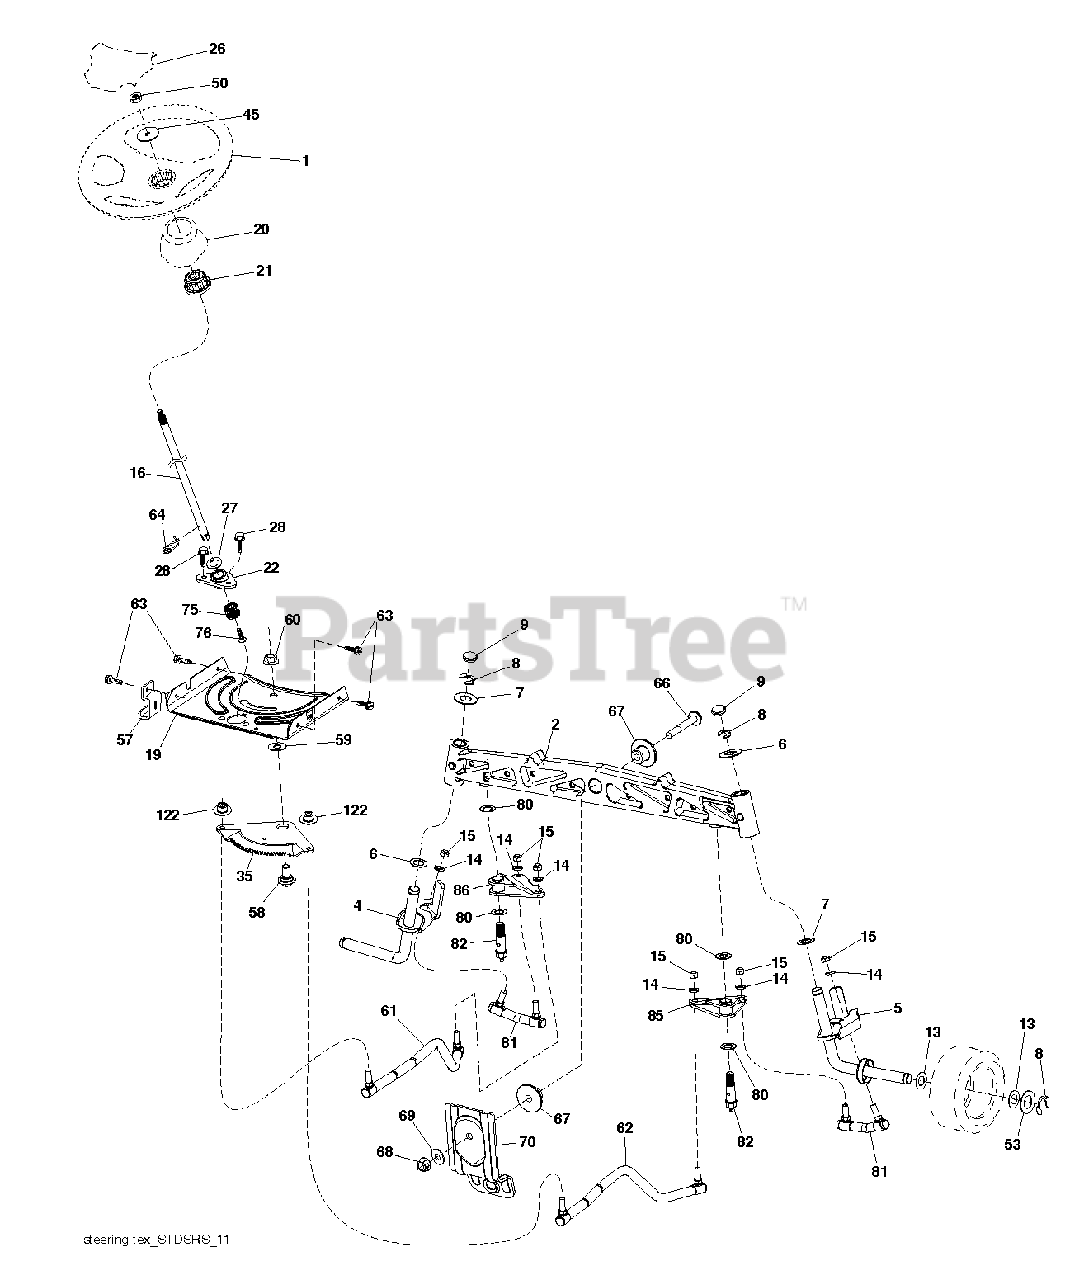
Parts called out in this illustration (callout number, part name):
1	WHEEL.STEERING.MLT.BR.YEL/OVRM
2	RP SUBASM.AXLE.CAST.N
4	SPINDLE WELDMENT.SPIN
5	SPINDLE WELDMENT.SPIN
8	RING CLIP
9	CAP.SPINDLE.BLACK
14	WASHER, LOCK 3/8
15	NUT CROWNLOCK 3/8-24
19	PLATE.STEER.DDL.NLT/NG
20	BOOT.STRNG.PREDATOR.YT/GT.428
26	CAP.WHL.STRNG.MULTI.BRND.YEL
27	WASHER LT
28	SCREW, 3/8-16X3/4
35	GEAR GEAR.SECTOR.TEX.
45	WASHER.3/8ID.2-3/8OD.12GA.PLTD
50	NUT LOCK FLG 3/8-16 UNC
53	WASHER.HARDENED
57	BRKT.UPSTOP.GT/LT.TEX
58	BOLT.SHOULDER.SECTOR.P
59	WASHER.THURST.SECTOR.S
60	NUT FLANGE LOCK 5/8-11
61	LINK SUBASM.LINK.DRAG
62	TUBE TUBE
63	SCREW
64	RETAINER.CLIP.SPRING.S
66	BOLT HEX FGHD 7/16-14 X 3 SERR
67	BUSHING.PM.FRONT AXLE
68	NUT.LOCK.FLANGE.7/16
69	WASHER.1.5X.505X.118
70	Deck Suspension Bracket, Front RR
76	Screw Head Socket Lrvb
80	THRUST WASHER
81	LINK SUBASM.LINK.CROS
82	SUBASM;PIVOT;BOLT;NZTR
85	PIVOT SUBASM.PIVOT.RH
86	PIVOT SUBASM.PIVOT.LH
122	CAP.GEAR.SECTOR.TEX
